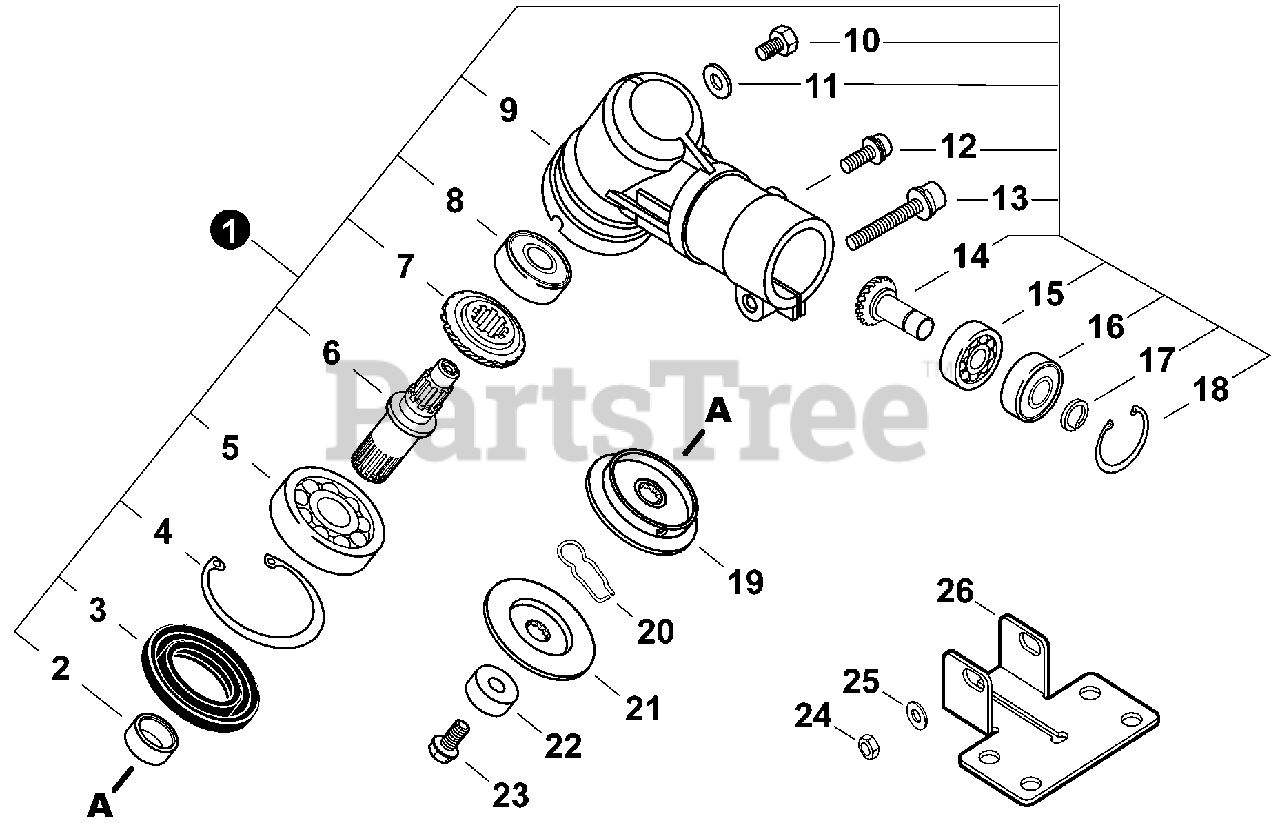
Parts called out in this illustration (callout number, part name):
1	GEAR CASE ASSY
2	COLLAR
3	SEAL, OIL
4	RING, SNAP ?35
5	BEARING, BALL 6202
6	SHAFT, GEAR
7	GEAR, BEVEL
8	BEARING, BALL 6000DDU
9	HOUSING, GEAR CASE
10	BOLT M6x10
11	WASHER
12	BOLT M6x14
13	BOLT M6x40
14	PINION ASSY, BEVEL
15	BEARING, BALL 6001
16	BEARING, BALL 6001ZZ
17	RING, SNAP 12
18	RING, SNAP ?28
19	PLATE, ADAPTOR - UPPER
20	PIN, SLIDE
21	PLATE, ADAPTOR - LOWER
22	GUARD, BOLT
23	BOLT 10x37
24	NUT, HEX M6
25	WASHER 6.5x13x1
26	CLAMP, LOWER
